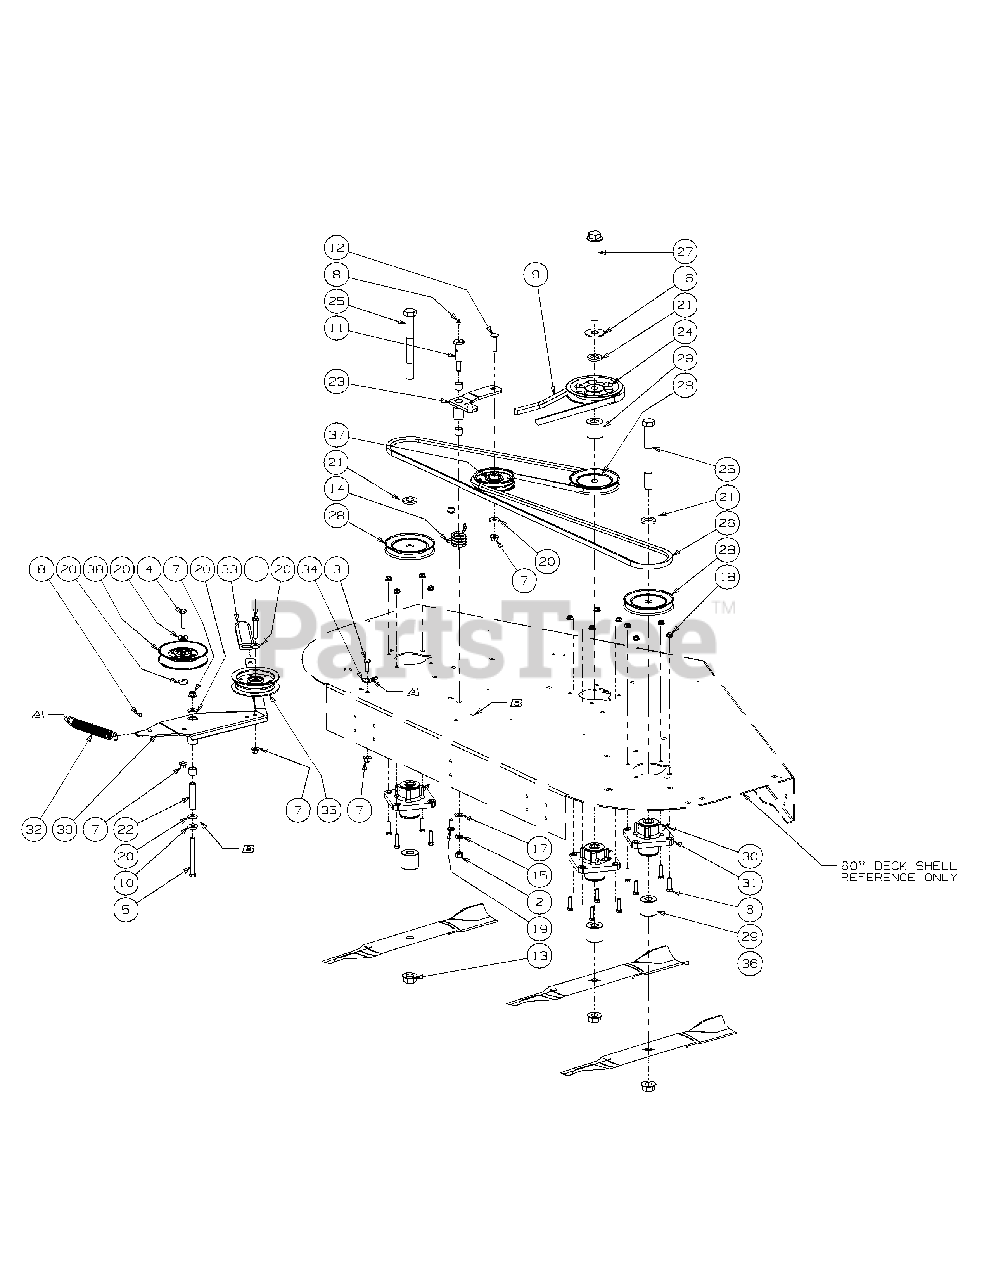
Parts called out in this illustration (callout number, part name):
1	Hex Cap Screw, 3/8-16 x 2.00
2	Hex Nut, 7/16-14
3	Hex Cap Screw, 3/8-16 x 1.00
4	Hex Cap Screw, 3/8-16 x 1-3/4
5	Hex Cap Screw, 3/8-16, 4.00
6	HHCS, 5/16-18 x 1-1/4
7	Flange Lock Hex Nut, 3/8-16
8	Grease Fitting, 1/4-28 x 3/16
9	V-Belt, B-Section, BK90
10	Idler Washer
11	Shoulder Screw, 7/16-14
12	Hex Carriage Screw, 3/8-16, 1.75
13	Flange Hex Nut, 3/4-16
14	Torsion Idler Spring
15	Lock Washer, 7/16
16	Flat Washer, .781 ID 2.00 OD, .105
17	Flat Washer, .469 ID, .875 OD, .105
18	Nut, 5/16-18, Flange Lock
19	Carriage Bolt, 3/8-16 x 1
20	Flat Washer, .406 ID, 1.0 OD, .105
21	Spacer .812 ID x .268 LG
22	Spacer, .39 ID x .625 OD x 2.75
23	Idler Arm Assembly, Deck Spindle includes:
24	V-Pulley, 5.774 OD
25	Hex Cap Screw, 3/4-16, 6.50
26	V-Belt, A Section x 122.3
27	Hex Cap Screw, 3/4-16, 9.00
28	V-Pulley, 4.9 OD
29	Spacer, .760 ID x 1.75 OD x 1.60
30	Grease Fitting, 45 Degree
31	Spindle Assembly
32	Extension Spring, .94 x OD x 7.57
33	Grip, 1.0 x 3.2 x .25
34	Tension Spring Bracket
35	Idler Pulley, 4.06 OD
36	Hi-Lift Blade, 21.0, 0.756 ID
37	Flat Pulley with Flanges
38	Idler Pulley, 5.06 OD
39	Idler Arm Assembly includes:
